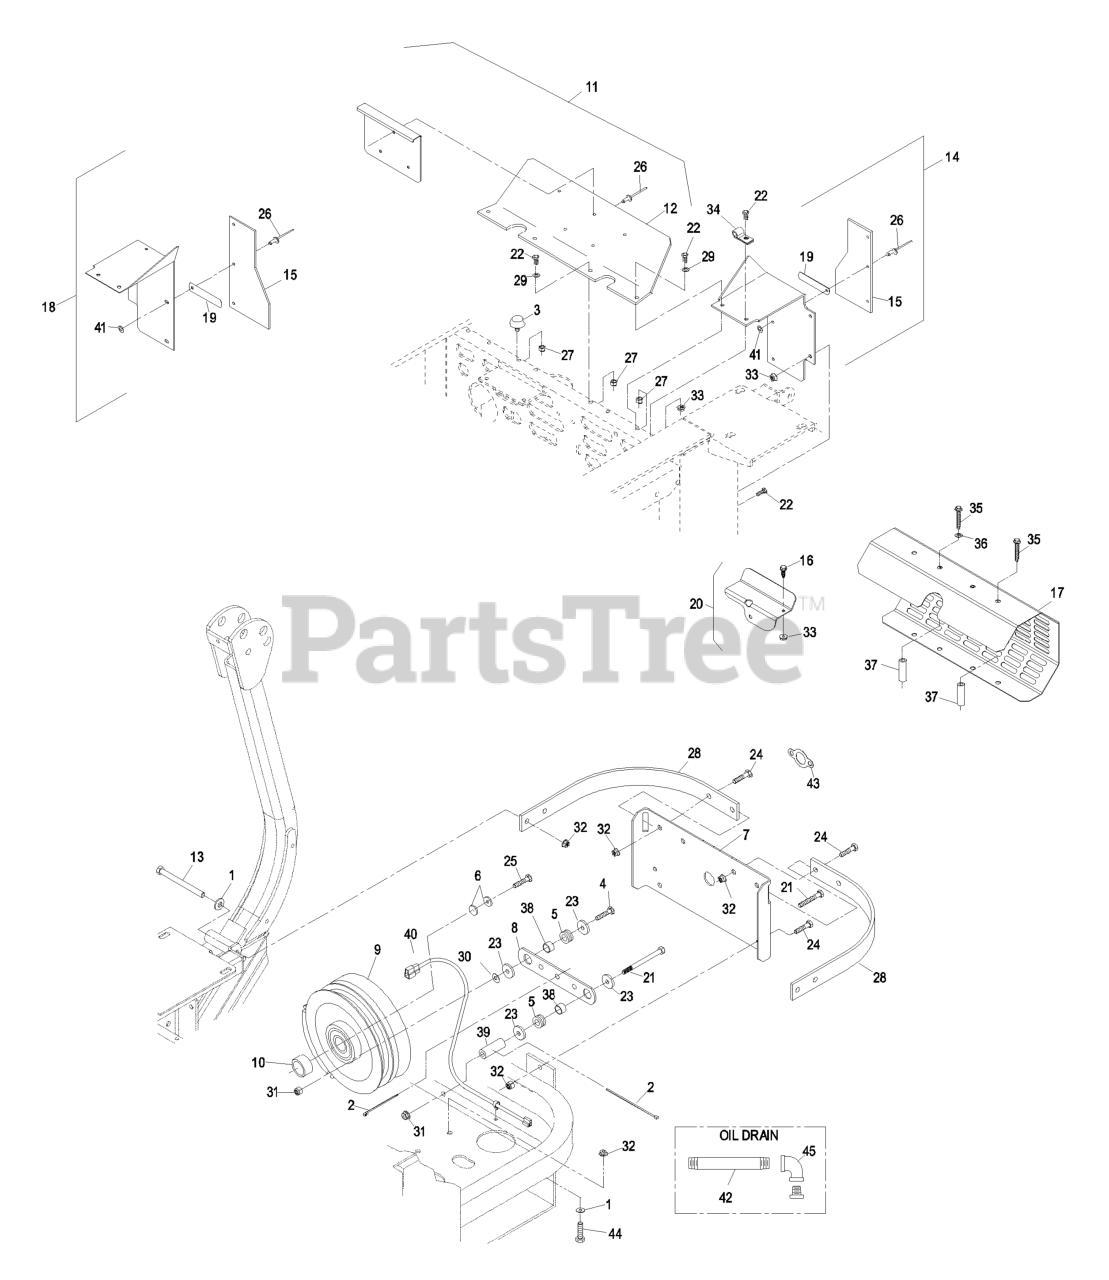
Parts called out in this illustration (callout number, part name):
1	WASHER-BELLEVILLE
2	TIE-PLASTIC
4	SCREW-HH
5	GROMMET
6	WASHER-SPRING
7	GUARD-CLUTCH
8	STRAP-CLUTCH, BRAKE
9	KIT-CLUTCH
10	SPACER-CLUTCH
12	SHIELD-ENGINE
13	SCREW-HH
15	SHIELD-ENGINE
16	SCREW-HH
17	GUARD-MUFFLER
18	RH SHIELD ASM
19	CLIP-BAFFLE, REAR
20	CABLE HEAT SHIELD KIT
21	SCREW-HH
22	SCREW-HH
24	SCREW-HH
25	SCREW-HH
26	RIVET-POP
27	NUT-LOCK, NI
29	WASHER-FLAT
30	WASHER-FLAT
32	NUT-HHF, WHIZ
34	CLIP-LOOM
36	WASHER-SPRING
39	SPACER-ANCHOR, CLUTCH
40	KIT,CLUTCH JUMPER HARNESS
41	WASHER-FLAT
42	NIPPLE
44	SCREW-HH
45	ELBOW-90 DEG
